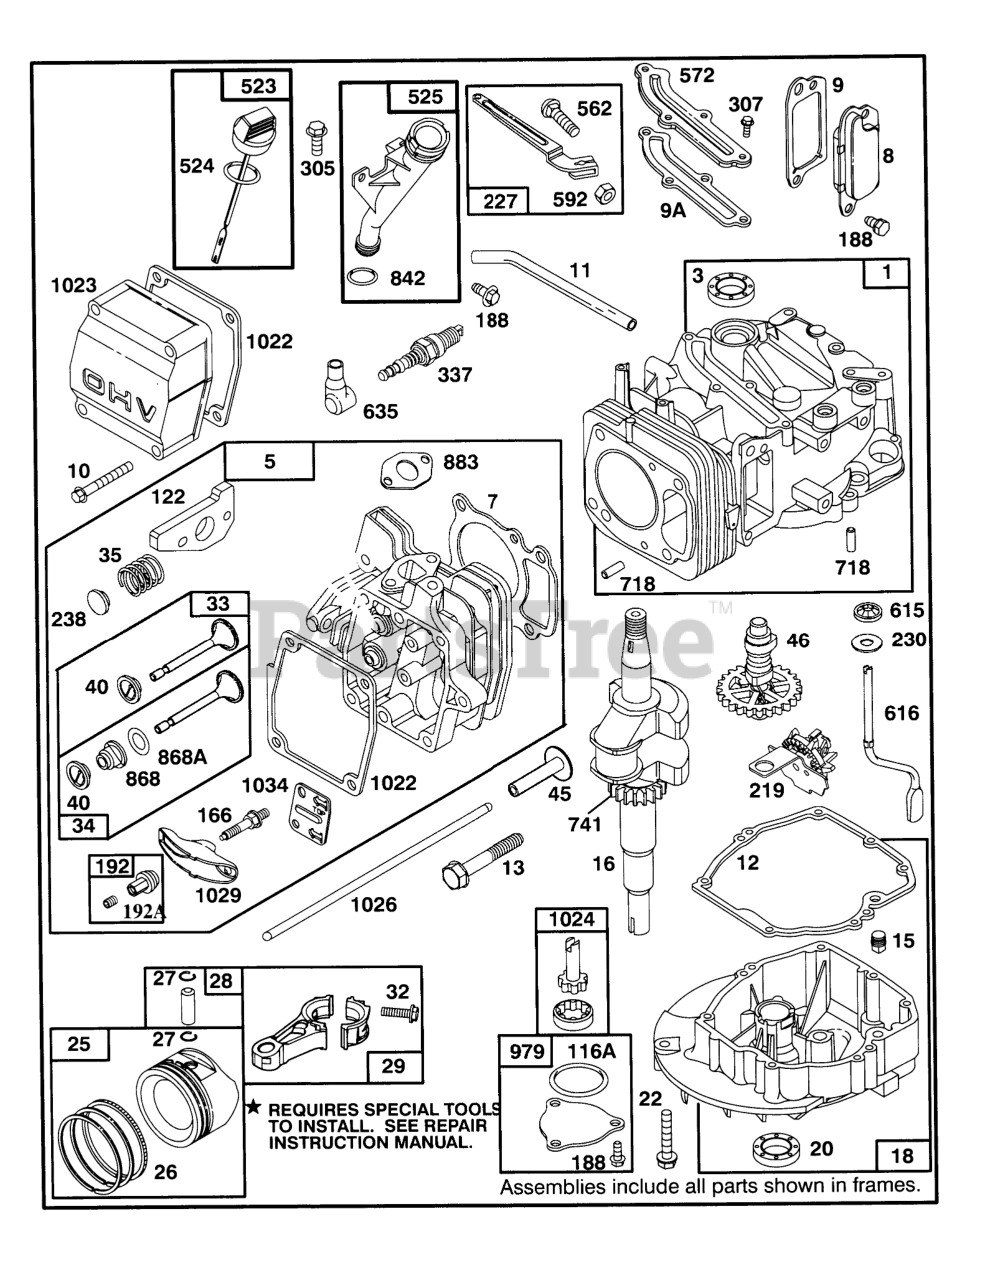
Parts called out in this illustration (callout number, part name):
1	CYLINDER ASSEMBLY
3	SEAL - OIL
5	CYLINDER HEAD
7	CYLINDER HEAD GASKET
8	BREATHER ASM
9	BREATHER GASKET
9A	GASKET-BREATHER
10	HEX HEAD SCREW
11	BREATHER TUBE
12	ENGINE BASE GASKET
13	CYLINDER HEAD SCREW
15	PIPE PLUG
16	CRANKSHAFT
18	ENGINE SUMP
20	SEAL-OIL
22	SCREW - ENGINE BASE
25	STD PISTON ASSEMBLY
26	STD RING SET
27	PISTON PIN LOCK
28	Pin Assy-Piston
29	CONNECTING ROD
32	Connecting Rod
33	EXHAUST VALVE
34	INTAKE VALVE
35	VALVE SPRING
40	SPRING RETAINER
45	VALVE TAPPET
46	CAM GEAR
116A	O RING SEAL
122	ADAPTER ASSEMBLY
166	ROCKER ARM STUD
188	SCREW - SEM
192	NUT - HEX SPECIAL
192A	Screw-Set
219	GOVERNOR/OIL SLINGER
227	GOVERNOR LEVER ASSEMBLY
230	WASHER
238	VALVE CAP
305	SCREW - HEX HEAD
307	SCREW - SEM
337	PLUG-SPARK
523	DIPSTICK-OIL
524	O-RING
525	OIL FILLER TUBE
562	GOVERNOR LEVER BOLT
572	BAFFLE - CYCLINDER
592	HEX NUT
615	FASTENER
616	GOVERNOR CRANK
635	SPARK PLUG ELBOW
718	DOWEL - SLEEVE
741	TIMING GEAR
842	O-RING
868	SealAssy-Valve
868A	Seal-Valve
883	EXHAUST GASKET
979	OIL PUMP COVER
1022	ROCKER COVER GASKET
1023	Cover-Valve
1024	OIL PUMP
1026	PUSH ROD
1029	ROCKER ARM
1034	PUSH ROD GUIDE
